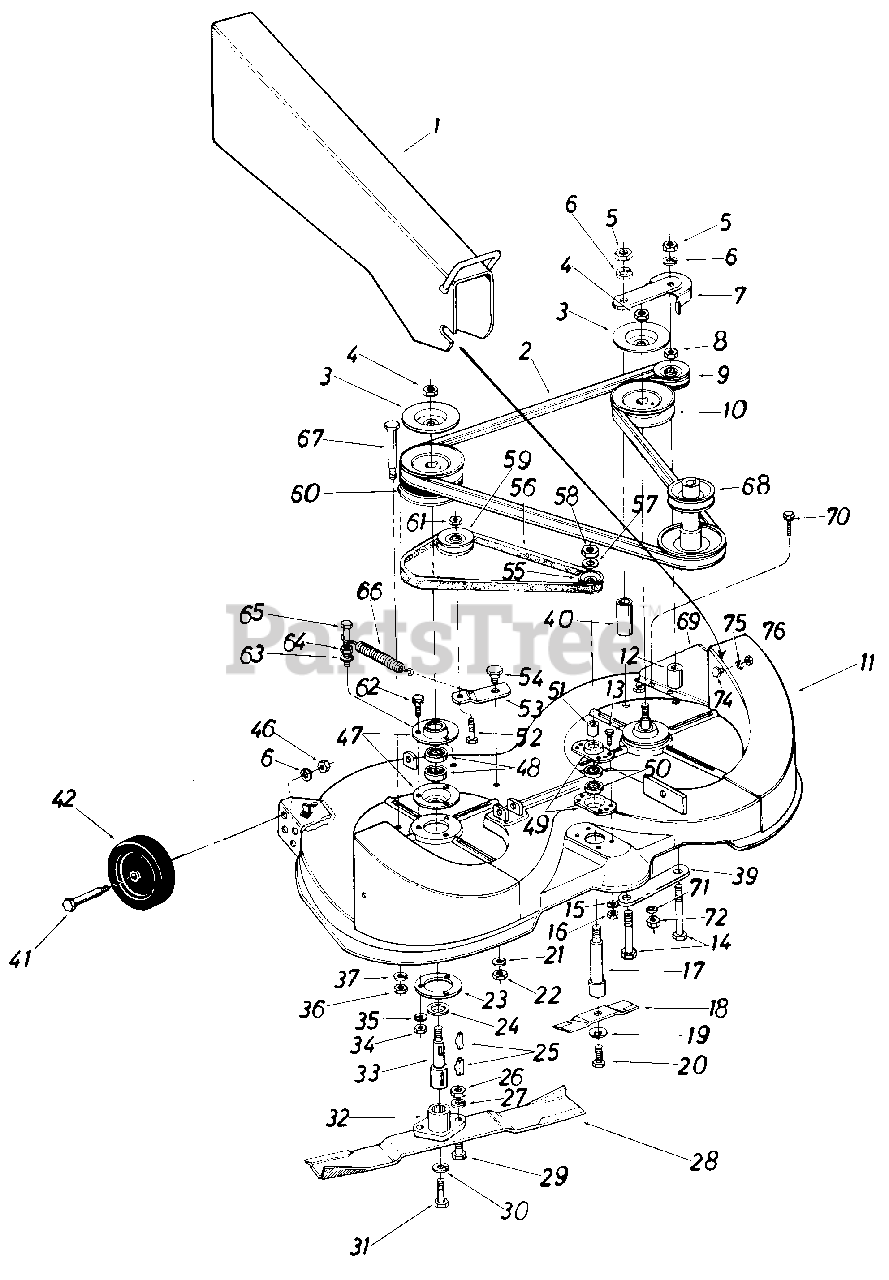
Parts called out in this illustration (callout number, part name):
1	Chute Extension Ass'y.-L.H.
2	"V"-Belt 1/2 x 84.0" Lg.
3	Brake Disc
4	Hex Cent. L-Nut 5/8-11 Thd.
5	Hex Jam Nut 3/8-16 Thd.
6	L-Wash. 3/8" I.D.
7	Idler Pulley Belt Guard Ass'y.
8	Hex Jam Nut 3/8-16 Thd.
9	5/8-V Belt Idler 3.50" O.D.
10	5/8-V Pulley-.628" I.D. x 5.25" O.D.
11	40" Rear Discharge Deck
12	Spacer.40" I.D. x 1.25" O.D. x 1.59" Lg.
13	Hex Sems Bolt 1/4-28 x .62" Lg.
14	Hex Bolt 3/8-16 x 3.75" Lg.
15	L-Wash. 1/4" I.D.
16	Hex Nut 1/4-28 Thd.
17	Blade Spindle
18	6.50" Blade
19	Bell-Wash. .40" I.D. x .88"O.D.
20	Hex Bolt 3/8-24 x .87" Lg.
21	L-Wash. 3/8" I.D.
22	Hex Nut 3/8-16 Thd.
23	Plate-Deck Reinforcement
24	Bearing Shield
25	#6 Hi-Pro Key 5/32 x 518" Dia.
26	Hex Nut 5/16-24 Thd.
27	L-Wash. 5/16" I.D.
28	20" High Lift Blade-R.H.
29	Hex Bolt 5/16-24 x 1.00" Lg. (Grade 5)
30	L-Wash. 3/8" I.D. Heavy Duty
31	Hex Bolt 3/8-24 x 1.50" Lg. (Grade 5)
32	Blade Adapter Kit
33	Blade Spindle
34	Hex Nut 5/16-18 Thd.
35	L-Wash. 5/16" I.D.
36	Hex Nut 3/8-16 Thd.
37	L-Wash. 3/8" I.D.
39	Reinforcement Plate
40	Spacer 3/8" I.D. x .50" O.D. x 2.72"
41	Shld. Bolt .498" Dia. x 1.53" Lg.
42	Cutting Deck Wheel
46	Hex Jam Nut 3/8-16 Thd.
47	Bearing Housing
48	Ball Bearing .787" I.D. x 1.85" O.D.
49	Bearing Housing
50	Ball Bearing .63" I.D. x 1.38" O.D.
51	Spacer.63" I.D. x .88" O.D. x 1.25" Lg.
52	Hex Bolt 3/8-16 x 1.25" Lg.
53	Idler Bracket
54	Shld. Bolt .625" Dia. x .170" Lg.
55	3/8" V-Pulley .628" I.D. x 2.00" O.D.
56	"V"-Belt 3/8 x 39.0" Lg.
57	Bell-Wash. .63" I.D. x 1.05" O.D.
58	Hex Jam Nut 5/8-11 Thd.
59	1/2" V-Belt Idler 2.625" O.D.
60	Double Pulley
61	Hex Top L-Jam Nut 3/8-16 Thd.
62	Hex Sems Bolt 5/16-18 x 1.00" Lg.
63	L-Wash. 1/4" I.D.
64	Hex Nut 1/4-20 Thd.
65	Hex Bolt 1/4-20 x 1.00" Lg.
66	Ext. Spring .50" O.D. x 3.97" Lg.
67	Shld. Bolt .498" Dia. x 2.63" Lg.
68	Two Step Engine Pulley
69	Inner Chute Extension-L.H.
70	Hex Sems Scr. 1/4-28 x .62" Lg.
71	L-Wash. 1/4" I.D.
72	Hex Nut 1/4-28 Thd.
74	Shld. Scr. .500" Dia. x .218
75	L-Wash. 3/8" I.D.
76	Hex Jam Nut 3/8-16 Thd.
